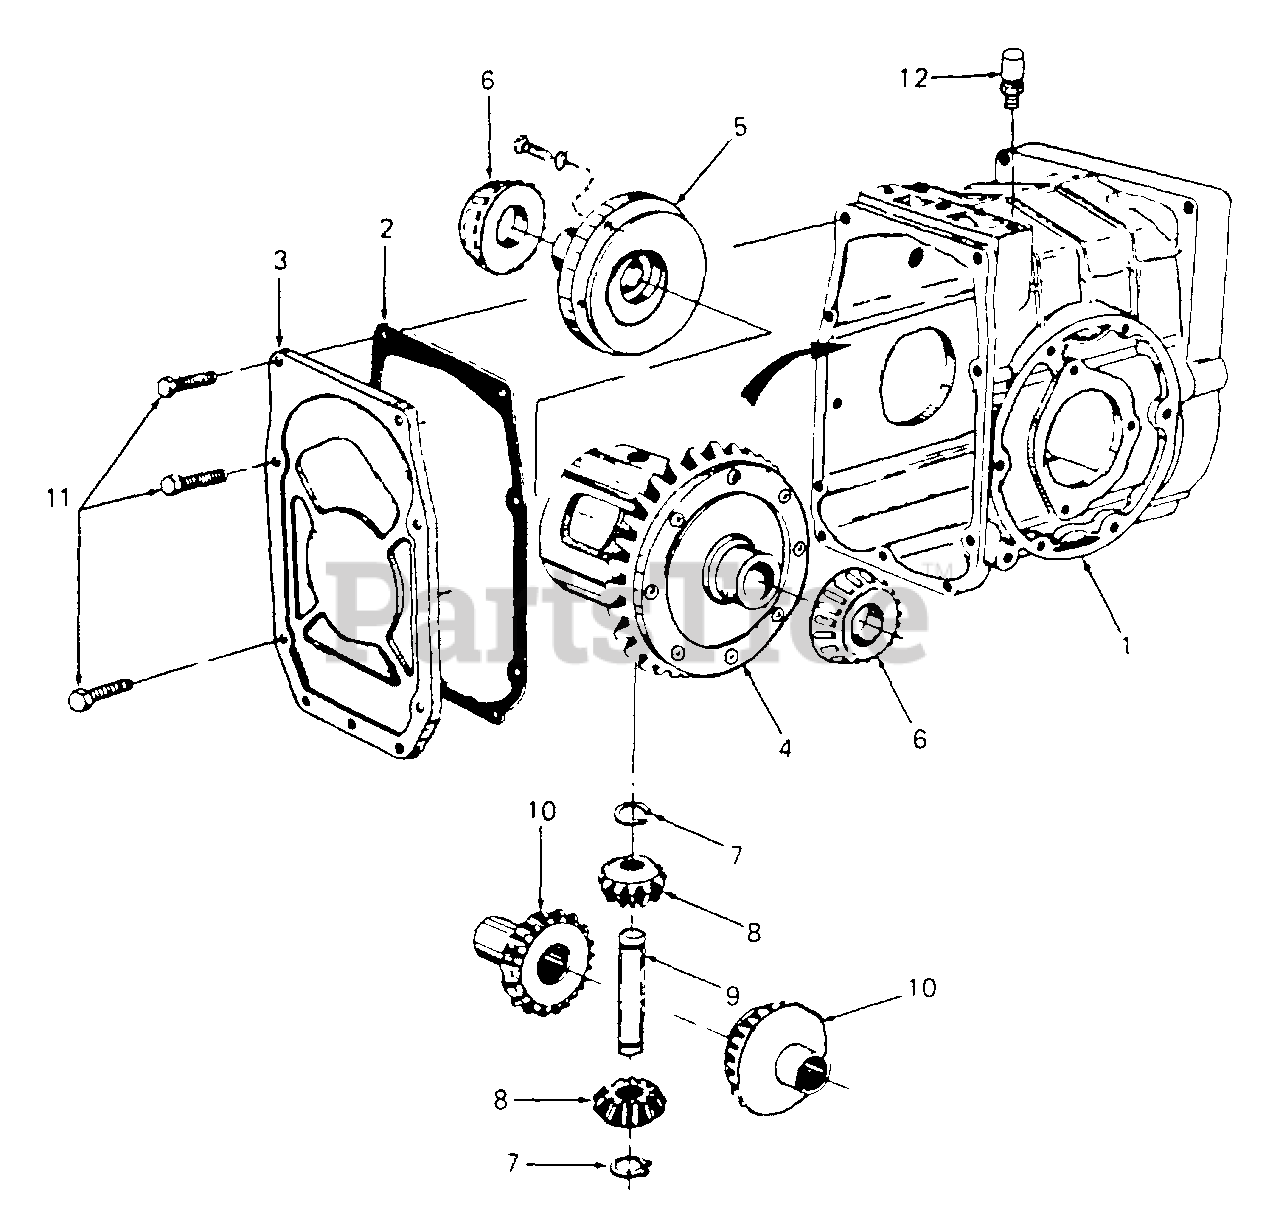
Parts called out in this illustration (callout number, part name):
1	Housing Assy, Rear Transaxle
2	Gasket, Rear Cover
3	Plate, Rear Cover
4	Gear Assy, Ring w/Case
5	Plate, Differential Flange
6	Cone, Roller Brg
7	Ring, Retaining, 11/16
8	Gear, Pinion - 10T
9	Shaft, Cross
10	Gear, Side - 16T
11	Bolt, Hex Patch, 3/8-16 x .62 Lg GR5
